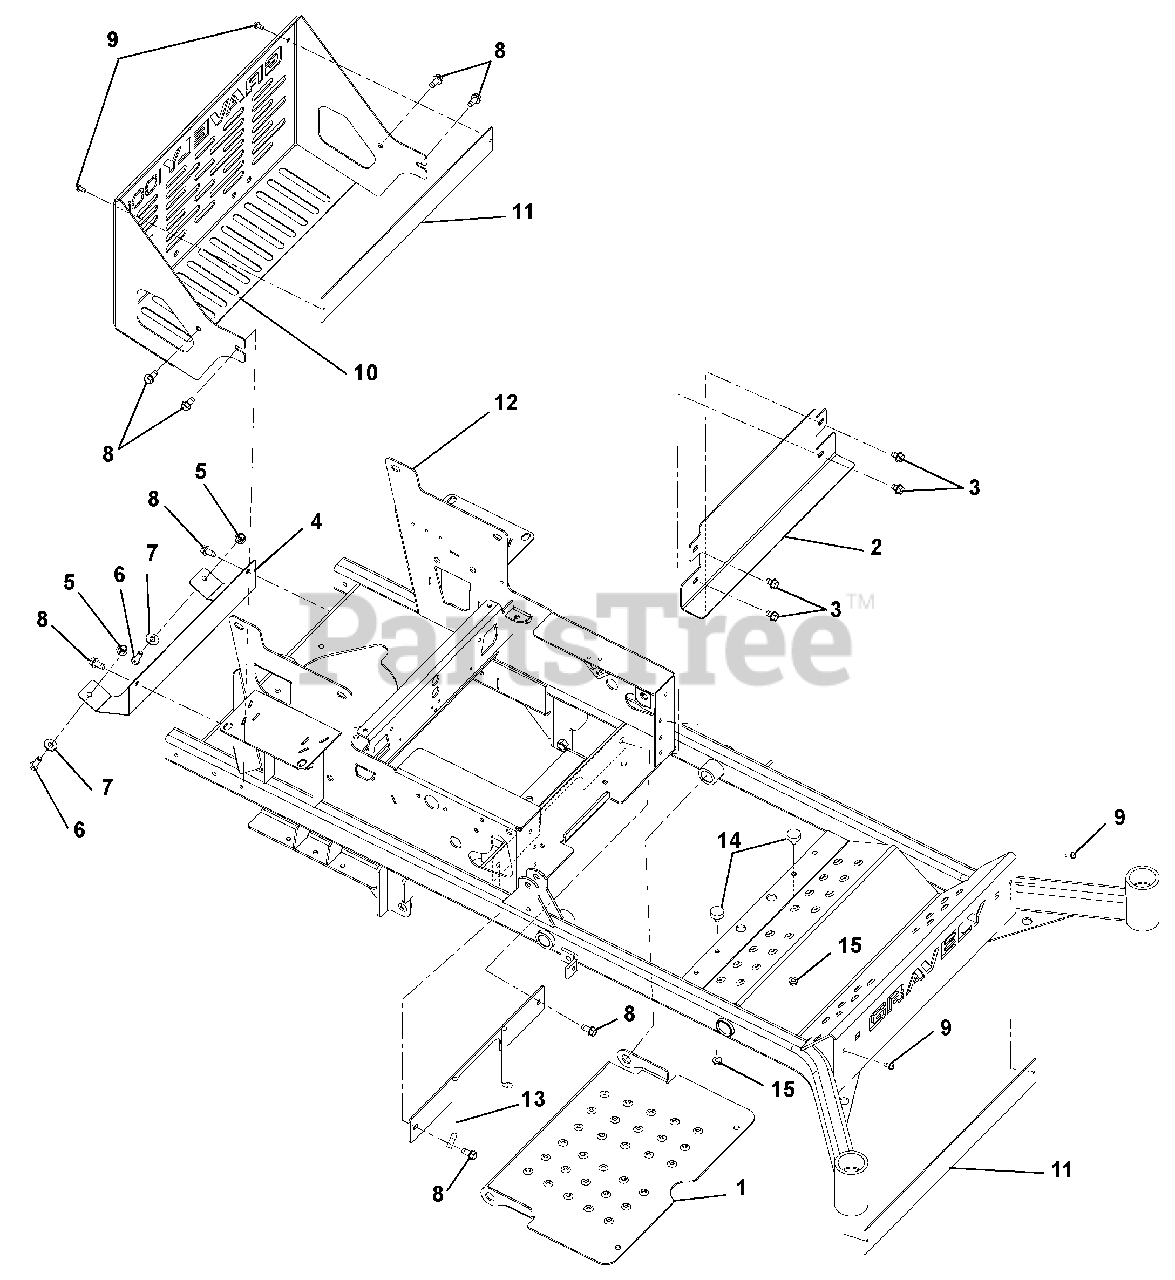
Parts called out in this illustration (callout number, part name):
1	100I Foot Plate
2	100I Kick Plate
3	Screw, Tapping .38-16 x .50 Hex Washer Head Thread Rolling
4	Shield, Heat- CZ PROD
5	Nut, .38-16 Nyloc Flange
6	Bolt, Hex .38-16X1.00 Grade 5
7	Washer, Flat-Steel .438 x 1.00 x .083
8	Screw, Tapping .38-16 x .75 Hex Washer Head Thread Rolling
9	Screw, Tapping .25-20 x .50 Hex Washer Head Thread Rolling
10	Gravely 100I Bumper
11	100I Bumper Name Back Plate
12	100I 60" Main Frame Weldment (067)
13	100I PTO Belt Finger Weldment
14	Bumper, Rubber
15	Nut, Spin Lock-Flange .312-18
